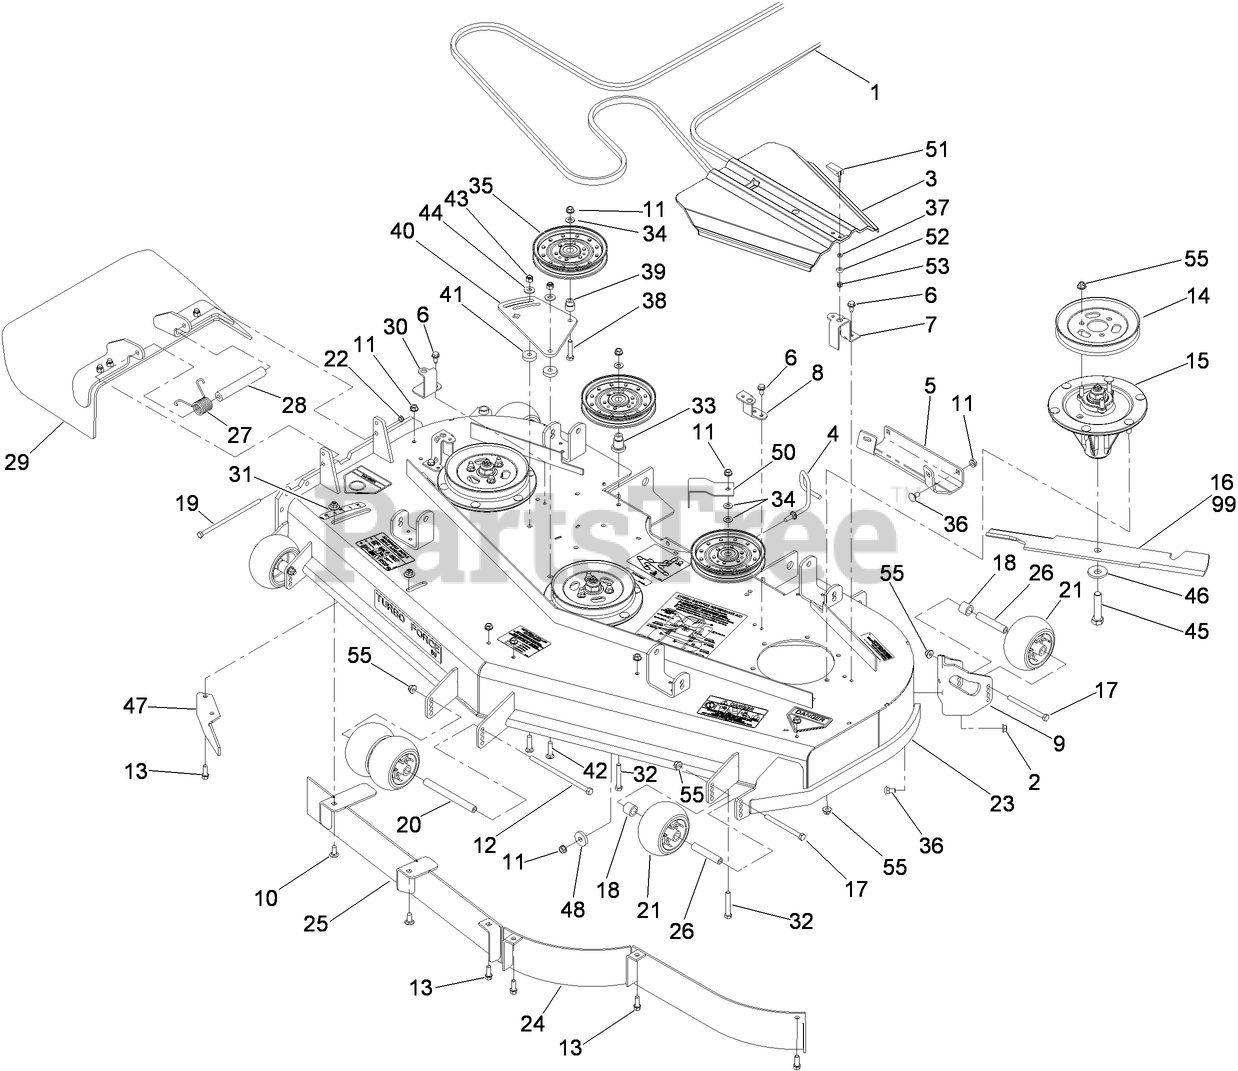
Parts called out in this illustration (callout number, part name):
2	NUT-LOCK, NI
3	COVER-BELT
4	GUIDE-BELT
5	Plate-Skid
6	SCREW-HWHTF
7	BRACKET-COVER
8	BRACKET-COVER, TALL
9	MOUNT-WHEEL, LH
10	SCREW-CARR
11	NUT-HHF, WHIZ
12	SCREW-HH
13	SCREW-HWH
14	Pulley
15	SPINDLE ASM
16	BLADE-HI FLOW
17	SCREW-HH
18	TUBE-SPACER
19	SCREW-HH
20	SPACER-WHEEL
21	ROLLER-SCALP, ANTI
22	NUT-LOCK, NI
23	DECK DECAL ASM
26	TUBE-SPANNER
27	SPRING-TORSION
28	SPACER
29	RUBBER DEFLECTOR ASM
30	BRACKET-COVER
31	NUT-FLANGE, NI
32	SCREW-HH
33	MOUNT-PULLEY
34	WASHER-FLAT
35	Idler-Flat
36	SCREW-CARR
37	WASHER
38	SCREW-HH
39	BUSHING-IDLER
40	Plate-Idler
41	Spacer
42	SCREW-CARR
43	NUT-LOCK, NI
44	WASHER-BELLEVILLE
45	SCREW-BLADE
46	Washer-Blade Bolt, Heavy
47	BAFFLE-DISCHARGE
48	WASHER
50	GUIDE-BELT
51	HANDLE-LATCH, SWELL
52	BUSHING-LATCH, SWELL
53	NUT-LOCK, HH
55	NUT-HF, NI
99	BLADE-MID FLOW, 20.5 INCH
99	BLADE-LO FLOW, 20.5IN
99	BLADE-RECYCLER, 20.5 INCH
99	BLADE-ATOMIC, 20.5IN
